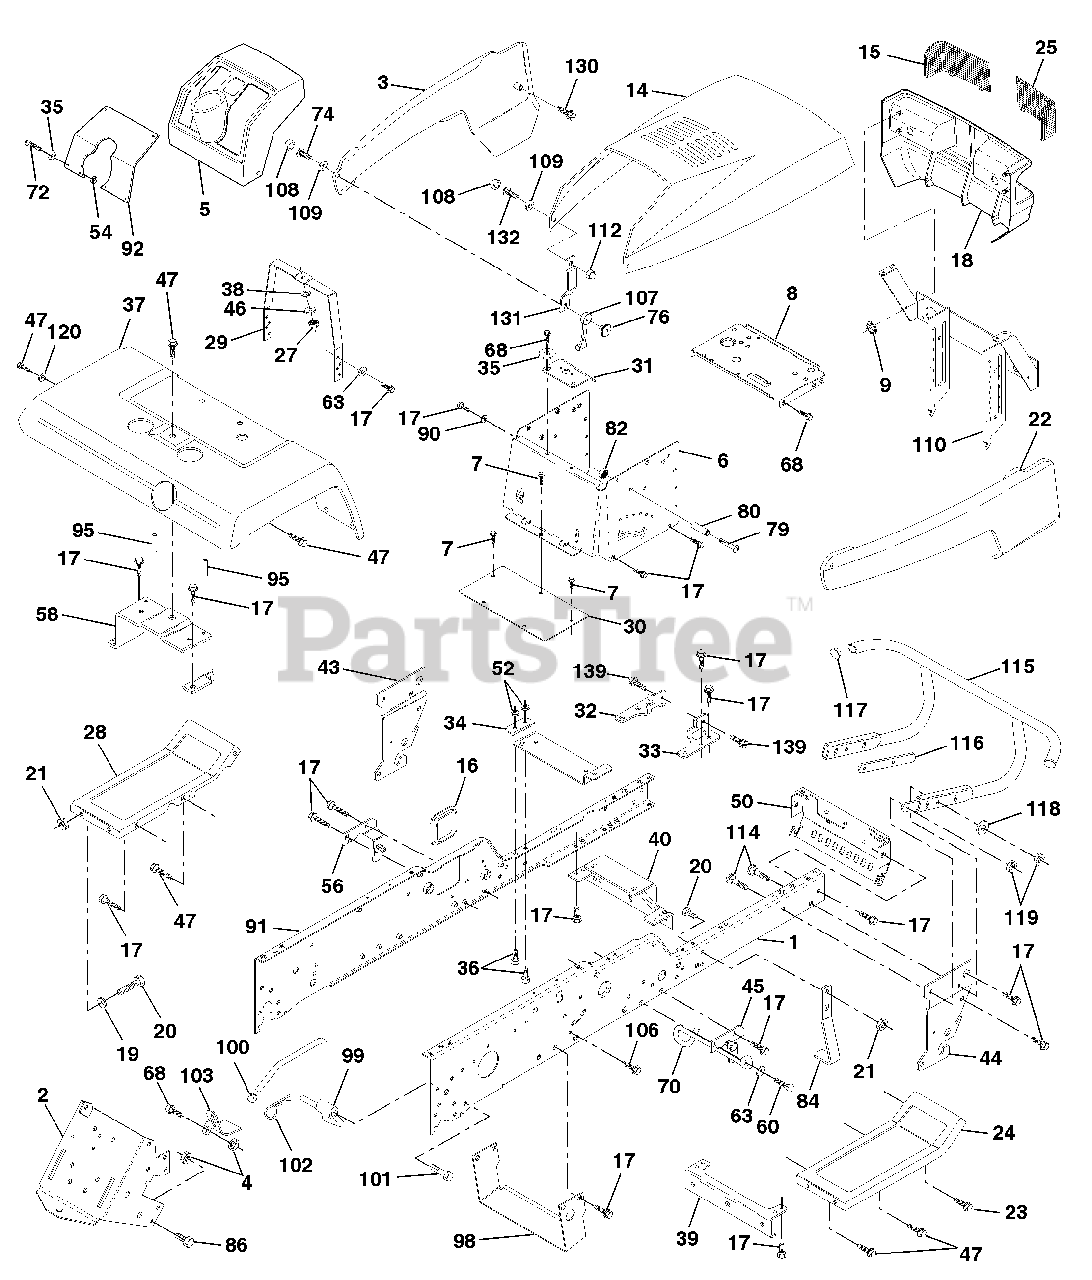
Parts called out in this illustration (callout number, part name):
1	Rail, Frame RH
2	Drawbar, Gt
3	Panel Asm., Side LH
4	Nut, Lock Hex 7/16 Unc
5	Dash, Plastic Black
6	Dash 1-PCS, Lower
7	Screw, Thd Cut 1/4-20 x 1/2
8	Support, Battery
14	Hood Asm., Pnt
15	Lens, Headlight LH
16	Cover, Access
17	Screw, Thdrol 3/8-16 x 3/4
19	Washer 13/32 x 13/16 x 12 Ga.
20	Bolt, Fin Hex 3/8-16 x 1
21	Nut, Crownlock 3/8-16 Unc
22	Panel Asm., Side RH
23	Screw Thdrol. 3/8-16 x 1 Ty-TT
24	Footrest, RH
25	Lens Headlight RH
27	Nut Fin Hex 1/4-20
28	Footrest, LH
29	Bracket, Support Dash
31	Brace, Support Steering
32	Bracket Asm., Frame Pivot Lh
33	Bracket Asm., Frame Pivot Rh
34	Bracket, Engine Support Rear
35	Washer 11/32 x 11/16 x 16 Ga.
36	Bolt, Fin Hex 5/16-18 x 3/4
37	Fender, Pnt.
38	Washer, Lock 1/4
39	Bracket, Axle Front
40	Bracket, Support Axle/Engine
43	Bracket, Spnsn Front Lh
44	Bracket, Spnsn Front Rh
45	Bracket Asm., Susp Chassis Rh
46	Washer 9/32 x 3/4 x 16 Ga.
47	Screw Thdrol 3/8-16 x 1/2
50	Bracket, Chassis Front
52	Locknut, Hex W/Ins 5/16-18 Unc
54	Nut 5/16-18
56	Bracket Asm., Susp Chassis Lh
58	Bracket Asm., Fender
60	Screw Thdrol 3/8-16 x 1-1/4
63	Washer 13/32 x 1 x 14 Ga.
68	Screw, Thdrol 5/16-18 x 1/2
70	Guide, Belt Mid Span
72	Screw, Mach Trhd 5/16-18 x 3/4
74	Screw, Machine #10-24
76	Nut, Weld #10-24
79	Screw, Machine #10-24 x 1/4
80	Spacer, Split
82	Nut #10-24
84	Stop, Over Center 44" 20/23" T. 94
86	Bolt, Fin Hex 7/16-14 Unc x 1
90	Washer, Lock External Tooth 3/8
91	Rail, Frame Lh
92	Plate, Silkscreen Dash
95	Push Nut, Nylon
98	Bracket Chassis Skid
99	Rod Asm. Bypass
100	Cap Brake Parking Red
101	Screw Thdrol. 3/8-16 x 1-3/4
102	Retainer Spring 1"
103	Bracket Lock Bypass
106	Screw Thdrol. Hex Hd Zinc Mur
107	Latch, Chute Blk
108	Cap, Snap Black
109	Cap, Washer Snap
110	Pivot Asm. Grille/Hood Husq. VGT
112	Nut, Acorn, Hex #10-24
114	Bolt, Carriage 3/8-16 x 1-1/4
115	Bumper Asm.
116	Bracket Extension Bumper
117	Plug Plastic
118	Washer 13/32 x 13/16 x 16 Ga.
119	Nut Crownlock 3/8-16 UNC
120	Washer 13/32 x 1 x 16 Ga.
130	Screw, SLTD Hex Hd. W/Pl Washer
131	Bracket Support Hood/Panel YP
132	Screw Truss Hd. #10-24 x 3/8
139	Bolt, Shoulder 5/16-18 TT
